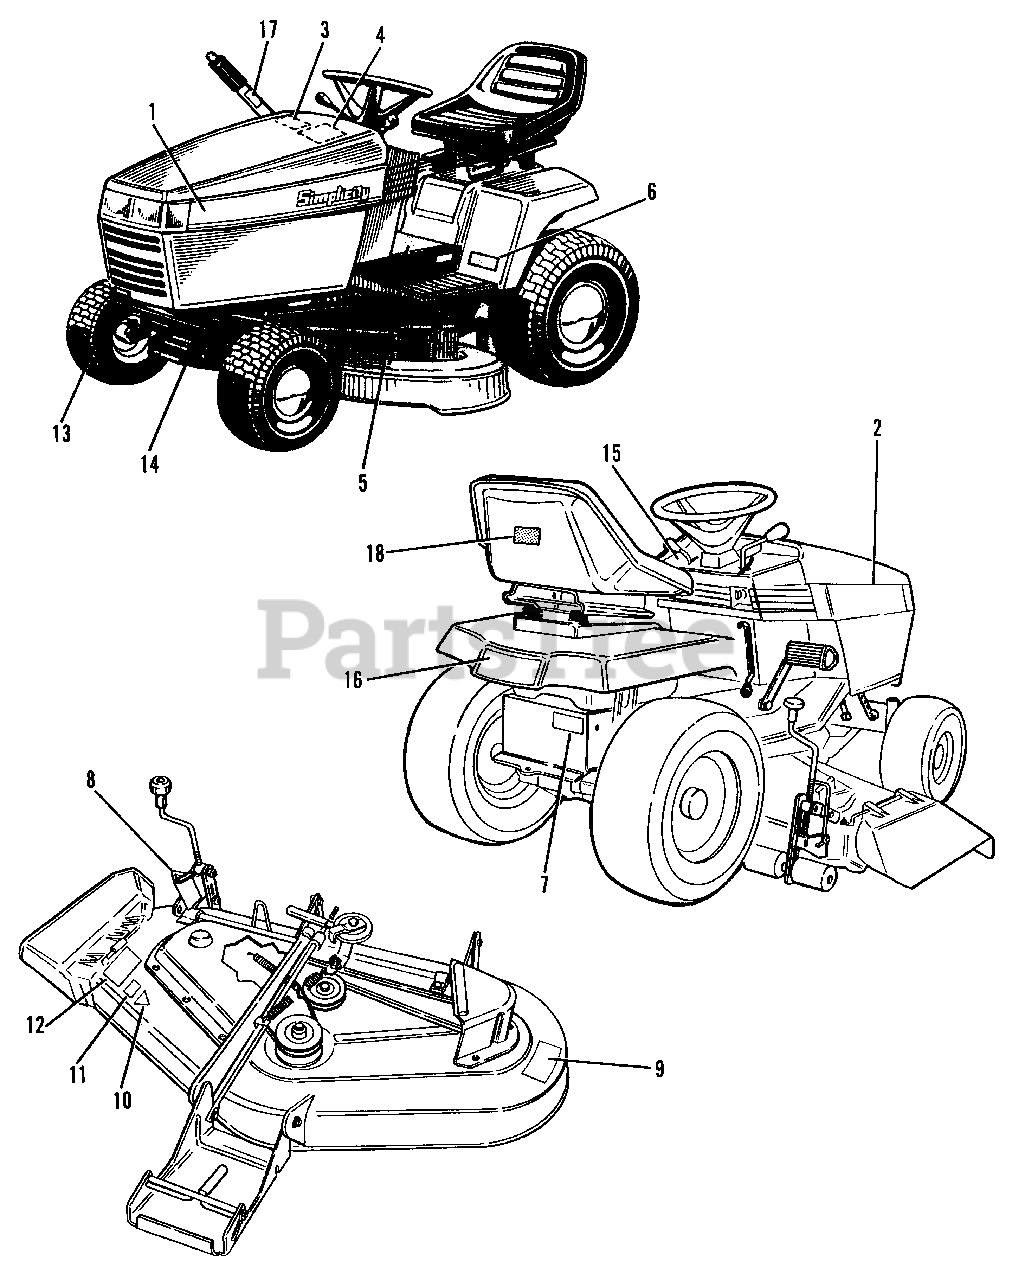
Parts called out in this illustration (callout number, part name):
1	DECAL, Hood, L.H., GT Models
1	DECAL, Hood, L.H., 18 HP Landlord
1	DECAL, Hood, L.H., 16 HP Landlord
1	DECAL, Hood, L.H., 14 HP Landlord
2	DECAL, Hood, R.H., GT Models
2	DECAL, Hood, R.H., 18 HP Landlord
2	DECAL, Hood, R.H., 16 HP Landlord
2	DECAL, Hood, R.H., 14 HP Landlord
3	DECAL, Paint
4	DECAL, Belt, Blade
5	DECAL, Operating Inst. (Hydro models only)
5	DECAL, Operating Inst. (Gear models only)
6	DECAL, 14 GTG (GT models only)
6	DECAL, 16 GTH (GT models only)
7	DECAL, Push Valve (Hydro models only)
8	DECAL, Mower Height
9	DECAL, Danger (Hand Under Deck)
10	DECAL, OPEI
11	DECAL, Cutting Width, 50"
11	DECAL, Cutting Width, 44"
12	DECAL, Danger (Chute in Place)
13	DECAL, Grille, Hot
14	I.D. PLATE
15	DECAL, Choke (Dash), (Gear models only)
16	DECAL, Simplicity
17	DECAL, Lift Lever (Gear models only)
18	DECAL, Logo U.S.A.
